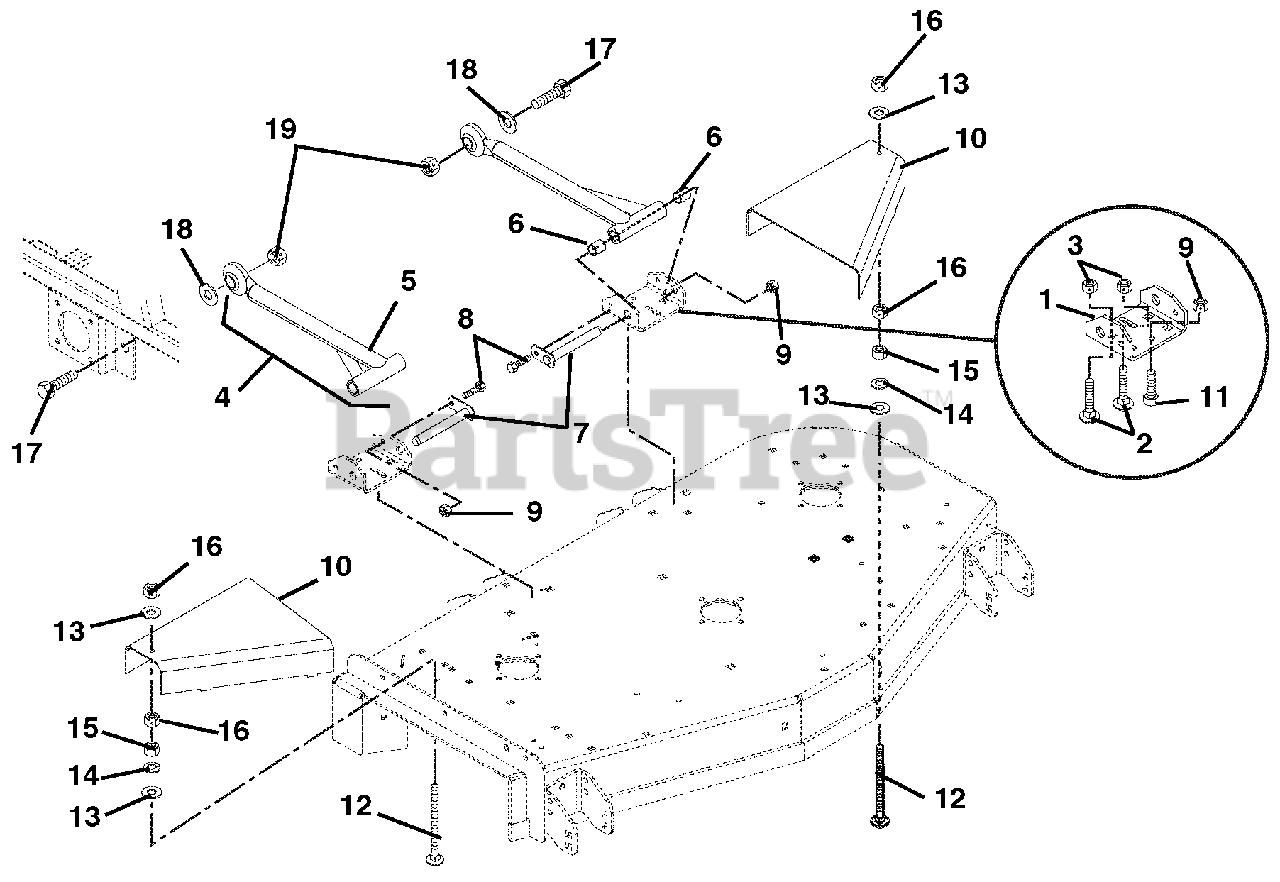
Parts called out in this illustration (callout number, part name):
1	Bracket, Mower Mounting (Rear)
2	Bolt, Round Head Square Neck .50-13 x .75 Grade 5
3	Nut, Locking Center Jam .50-13
4	Assembly, Mower Mounting Arm (Includes Items 5 and 6)
5	Weldment, Mower Mounting Arm
6	Bearing .75 x .875 x 1.00
7	Weldment, Mower Mounting Pin
8	Bolt, Hex .38-16 x 1.00 Grade 5
9	Nut, Locking Top Flange .38-16
10	Guard, Pulley Left Hand
11	Bolt, Round Head Square Neck .38-16 x .75 Grade 5
12	Bolt, Round Head Square Neck Full Thread .312-18 x 3.50
13	Washer, Flat Steel .344 x .688 x .06
14	Washer, Locking .31 x .078
15	Nut, Hex .31-18
16	Nut, Locking Center .31-18
17	Bolt, Hex .875-9 x 2.75 Grade 5
18	Washer, Flat Steel .875 x 1.50 x .120
19	Nut, Locking Center .875-9
